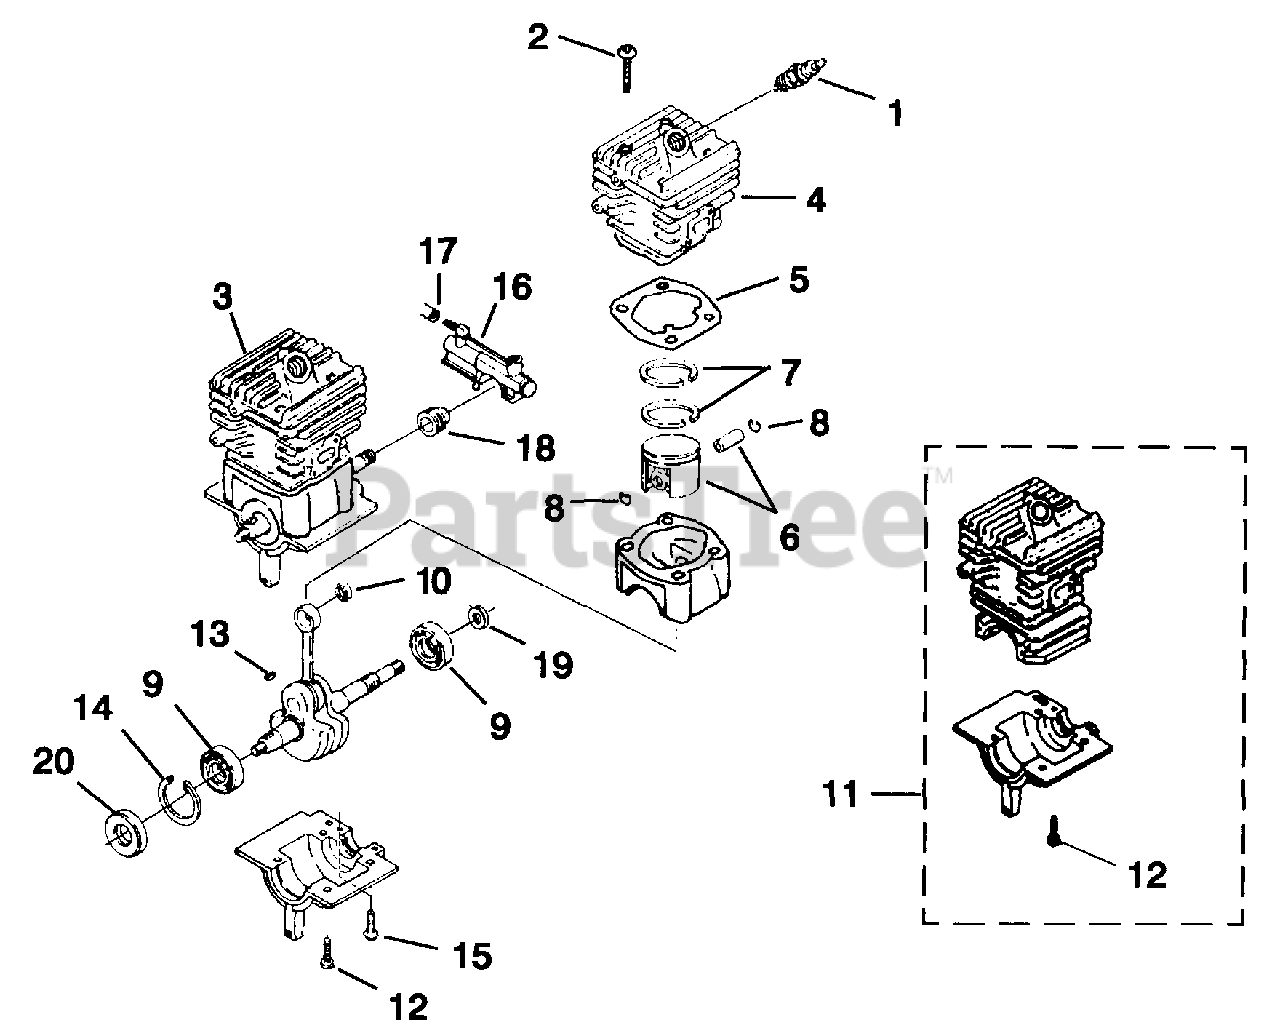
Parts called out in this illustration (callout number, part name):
1	SPARK PLUG (CJ6Y)
2	SCREW-PAN Hd. (10-24 x .800)
3	SHORT BLOCK
4	CYLINDER & GASKET
5	GASKET, CYLINDER
6	PISTON & PIN
7	RING, PISTON
8	RING, WRIST PIN RETAIN.
9	BEARING, BALL
10	BEARING, NEEDLE
11	CYLINDER & CRANKCASE
13	KEY WOODRUFF
14	RETAINING RING
15	SCREW, FIL. HD. (8-32 X 5/8")
16	OIL PUMP
17	TUBING, OIL (TO GUIDE BAR)
18	WORM GEAR, LEFT HAND
19	SEAL, CRANKSHAFT
20	SEAL, SHAFT
